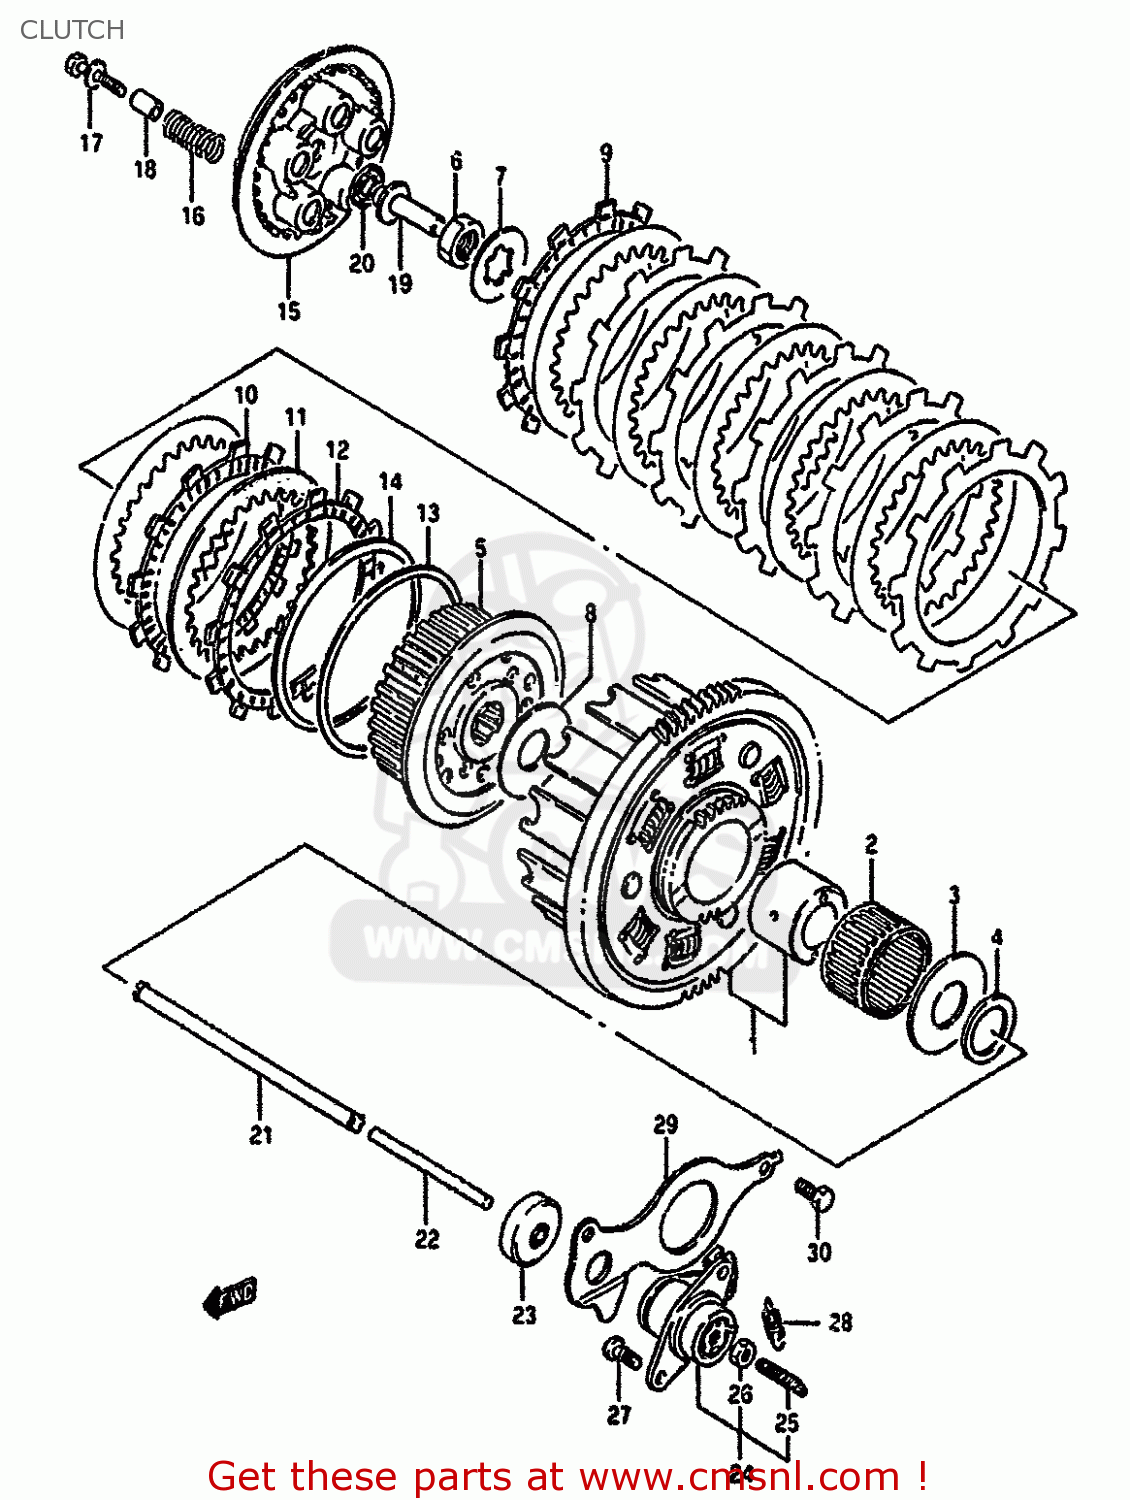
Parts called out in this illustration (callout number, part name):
1	GEAR ASSY,PRI DRIVEN
2	BEARING(37X42X27)
3	WASHER,22X50X2.5
4	WASHER(22X32X3)
5	HUB,CLUTCH SLEEVE
6	NUT
7	WASHER,LOCK
8	WASHER(20X50X2)
9	PLATE,CLUTCH DRIVE(T:3.0) (NAS)
10	PLATE,CLUTCH DRIVE (NAS)
11	PLATE,CLUTCH DRIVEN (NAS)
12	PLATE,CLUTCH DRIVE (NAS)
13	SEAT,WAVE WASHER
14	WASHER
15	DISC,CLUTCH PRESSURE
16	SPRING
17	BOLT(5X40)
18	SPACER (5.5X9.5X22)
19	PIECE,CLUTCH PUSH
20	BEARING(10X22X2.8)
21	ROD,CLUTCH PUSH
22	ROD,CLUTCH PUSH,L
23	SEAL,OIL(6X34X7.5)
24	SCREW ASSY,CLUTCH RELEASE
25	SCREW(6X25)
26	NUT 6MM
27	SCREW 6X12
28	SPRING
29	PLATE,CLUTCH PUSH ROD
30	BOLT
